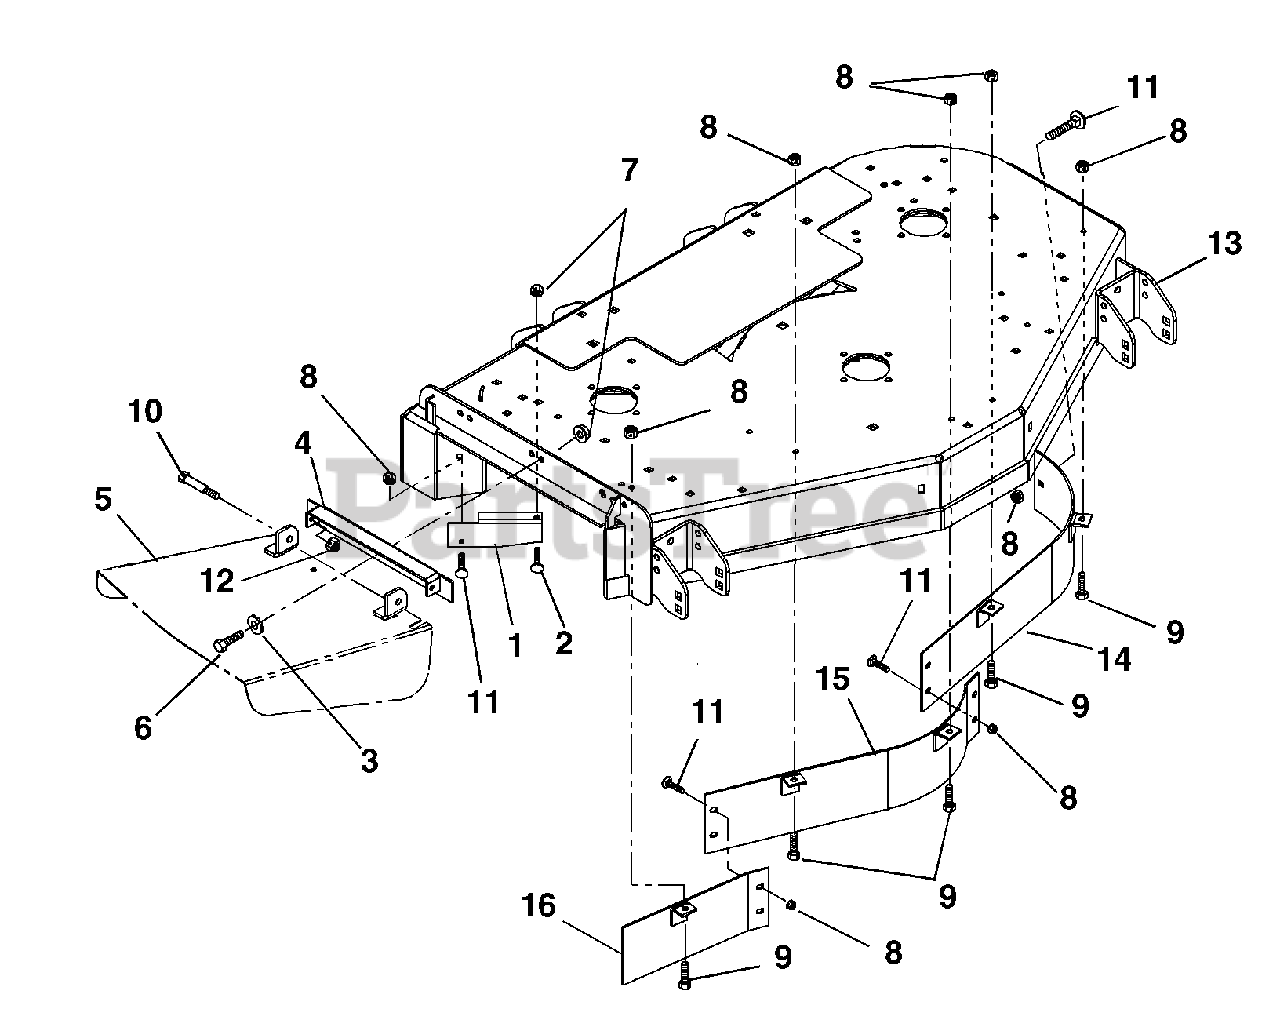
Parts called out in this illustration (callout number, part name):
1	Deflector, 52" (079, 081)
1	Deflector, 60" (080, 082)
1	Deflector, 44" (077, 078, 310, 311)
2	Bolt, Round Head Square Neck .38-16 x 1.00 Grade 5
3	Washer, Flat Steel .38 x .875 x .083 (077, 078, 079, 081, 310, 311)
4	Weldment Discharge Chute Bracket (077, 078, 079, 081, 310, 311)
4	Weldment Discharge Chute Bracket (080, 082)
5	Chute, Discharge (310, 311)
5	Chute, Discharge (080, 082)
5	Chute, Discharge (077, 078, 079, 081)
6	Bolt, Hex .38-16 x 1.00 Grade 5
7	Nut, Locking Top Flange .38-16
8	Nut, Locking Top Flange .31-18
9	Bolt, Hex .31-18 x .75 Grade 5
10	Bolt, Shoulder .38-16 x .50 Socket Head
11	Bolt, Round Head Square Neck .31-18 x .75 Grade 5
12	Nut, Locking Center .38-16
13	Weldment, 52" Mower Deck (079, 081)
13	Weldment, 60" Mower Deck (080, 082)
13	Weldment, 44" Mower Deck Float (077, 310)
13	Weldment, 48" Mower Deck (078, 311)
14	Baffle, Left Front - 52" (079, 081)
14	Baffle, Left Front - 60"(080, 082)
14	Baffle, Left Front - 44" (077, 310)
14	Baffle, Left Front - 48" (078, 311)
15	Weldment, Baffle Center Front - 52" (079, 081)
15	Weldment, Baffle Center Front - 60" (080, 082)
15	Weldment, Baffle Center Front - 44" (077, 310)
15	Weldment, Baffle Center Front - 48"(078, 311)
16	Weldment, Baffle Right Front - 52" (079, 081)
16	Weldment, Baffle Right Front - 60" (080, 082)
16	Weldment, Baffle Right Front - 44" (077, 310)
16	Weldment, Upper Baffle Right - 48"(078, 311)
